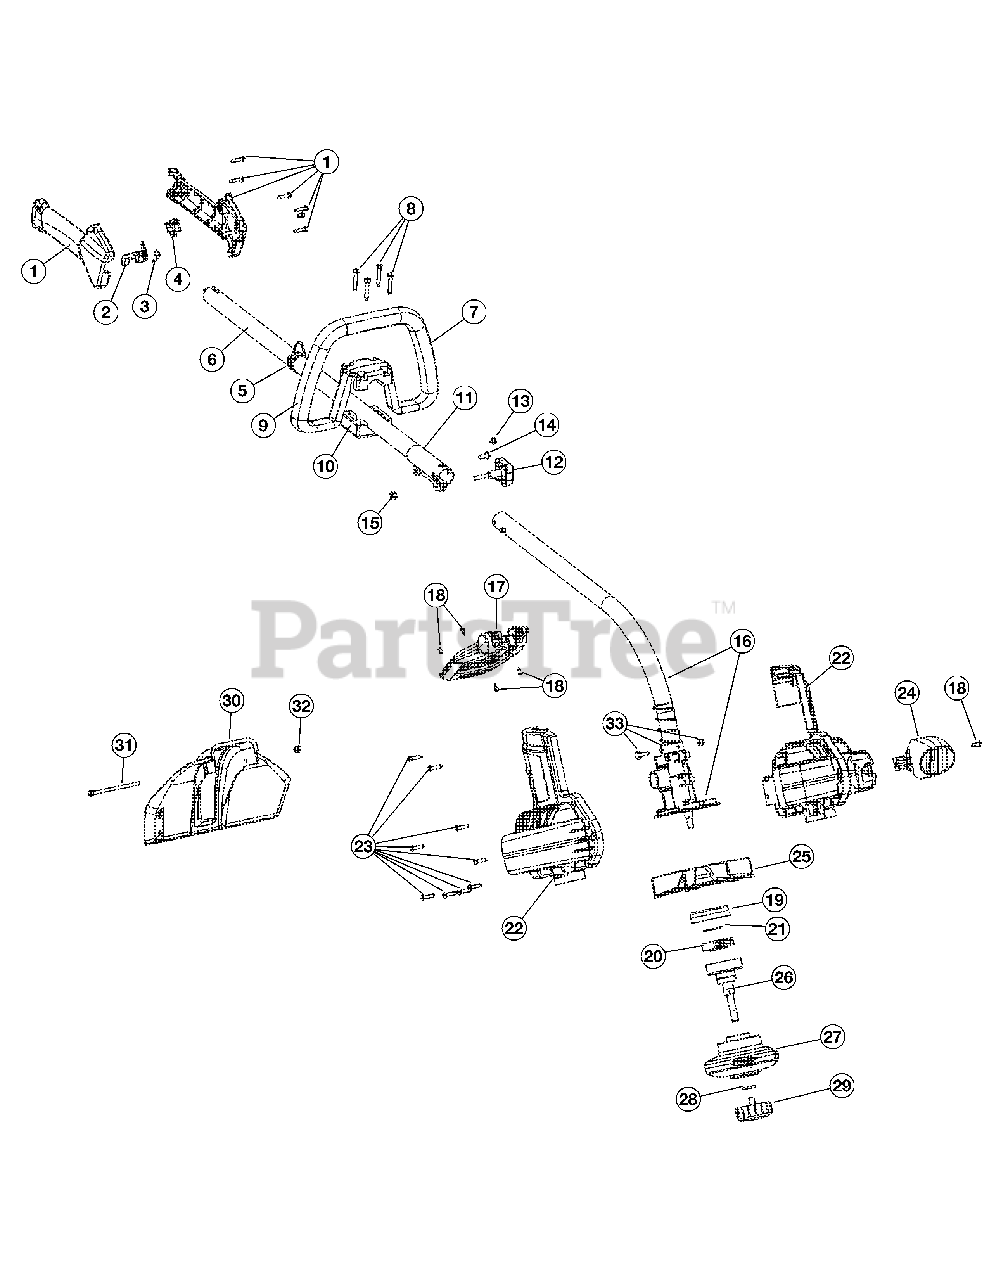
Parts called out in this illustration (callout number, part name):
1	Throttle Housing Assembly (includes 2-4)
2	Throttle Trigger
3	Throttle Trigger Spring
4	Switch Assembly
5	Harness Clip
6	Upper Drive Shaft Housing Assembly
7	Deluxe D-Handle Assembly (includes 8-10)
10	D-Handle Base
11	Split Boom Coupler (includes 12-15)
12	Adjustment Knob (includes 15)
15	Nut
16	Lower Drive Shaft Housing Assembly (includes 33)
17	Shift Handle Assembly (includes 18)
18	Screw
19	Clutch Drum Container
20	Clutch Assembly
21	Washer
22	Housing Assembly (includes 23)
23	Screw
26	Clutch Drum Assembly w/Spool Shaft
27	Fixed Line Head
28	Washer
29	Bump Knob Assembly
30	Guard Assembly w/Blade (includes 31 & 34)
31	Screw
32	Nut
